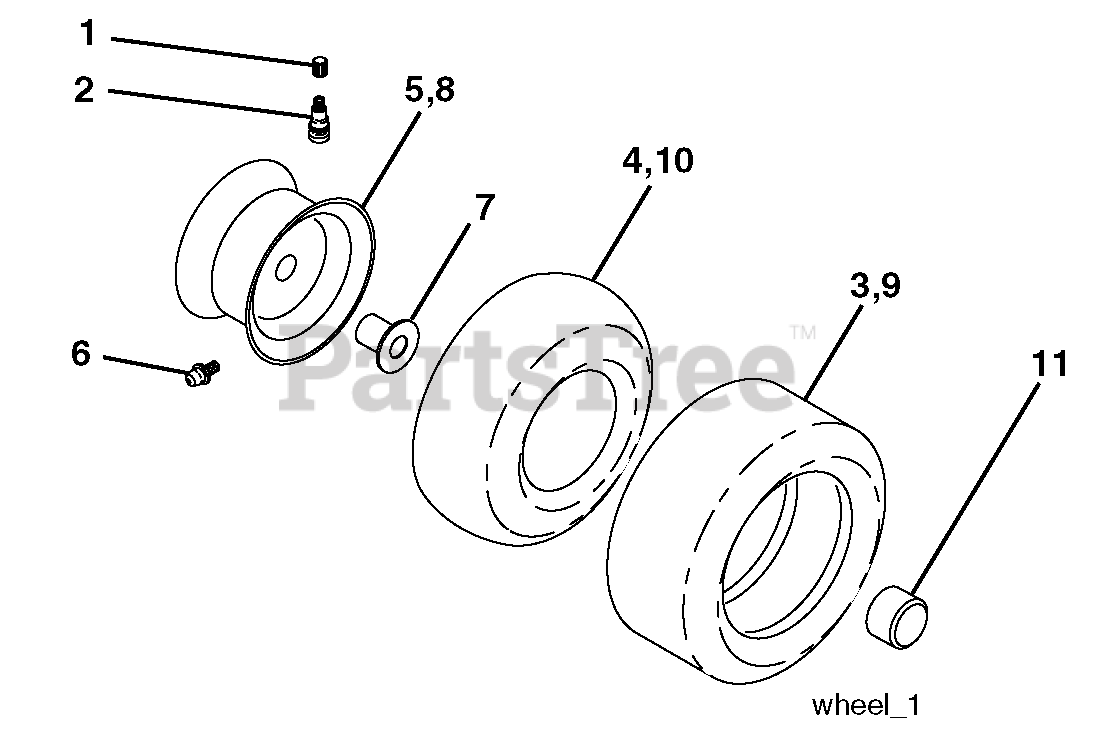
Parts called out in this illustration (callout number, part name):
1	Cap, Tire valve
2	Stem, Valve
3	Tire, Front
4	Tube, Front
5	Rim Assembly, 6" Front
6	Fitting, Grease
7	Bearing, Flange
8	Rim Assembly, 8" Rear
9	Tire, Rear 18 x 9.5-8 Turf Saver
9	Tire, Rear 18 x 9.5-8 Turf Saver LT
10	Tube, Rear
11	Cap, Hub Axle
11	Sealant, Tire (10 oz. Tube)
